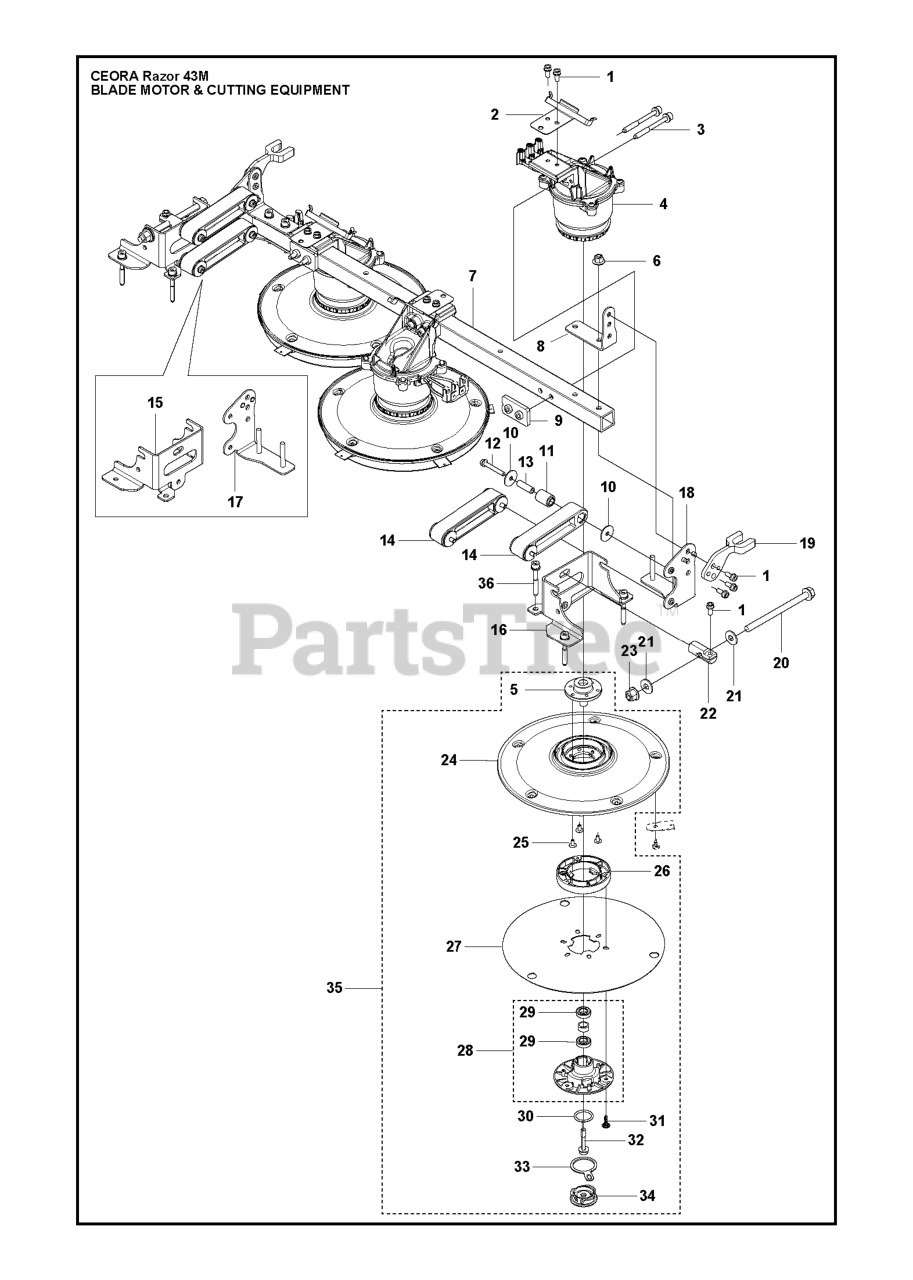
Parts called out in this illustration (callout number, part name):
1	SCREW
2	BRACKET MOTOR ASSY
3	SCREW ISO 10644 M6X60-10.9-S1
4	MOTOR ASSY MOTOR ASSY 14.5 STA
5	HUB CUTTING MOTOR P3
6	NUT FLANGE
7	BEAM 25X25X3
8	SUPPORT GABLE
9	PLATE SUPPORT WITH NUTS
10	WASHER 5.5X22X1.5 ST ZPB
11	BUSHING SILENTBLOCK
12	SCREW
13	SLEEVE D8-D5 L=25
14	LINK ARM HEIGHT ADJUSTMENT PAR
15	BRACKET HEIGHT ADJUSTMENT RIGH
16	BRACKET HEIGHT ADJUSTMENT LEFT
17	BRACKET GABLE RIGHT
18	BRACKET GABLE LEFT
19	BRACKET HEIGHT ADJUSTMENT LIFT
20	SCREW ISO 15071 M8X110 8.8 ZN/
21	WASHER ROUND 8.4X20X2 NYLON
22	BRACKET LINK NUT ANGLE ADJUSTM
23	NUT FLANGE
24	CUTTING DISC P3
25	SCREW HEXAGON SOCKET BUTTON HE
26	RING SKID PLATE
27	SKID PLATE P3
28	BEARING HOUSING ASSY SKID PLAT
29	BALL BEARING 2 RS,TIGHT CLEAR
29	BALL BEARING BALL BEARING 535
30	O-RING 20X2,5 MM
31	SCREW 14MM
32	RETAINER SCREW - CUTTING DISC
33	STRAP CAP
34	CAP SKID HUB
36	SCREW ISO 10644 M6X45-10.9-S1
